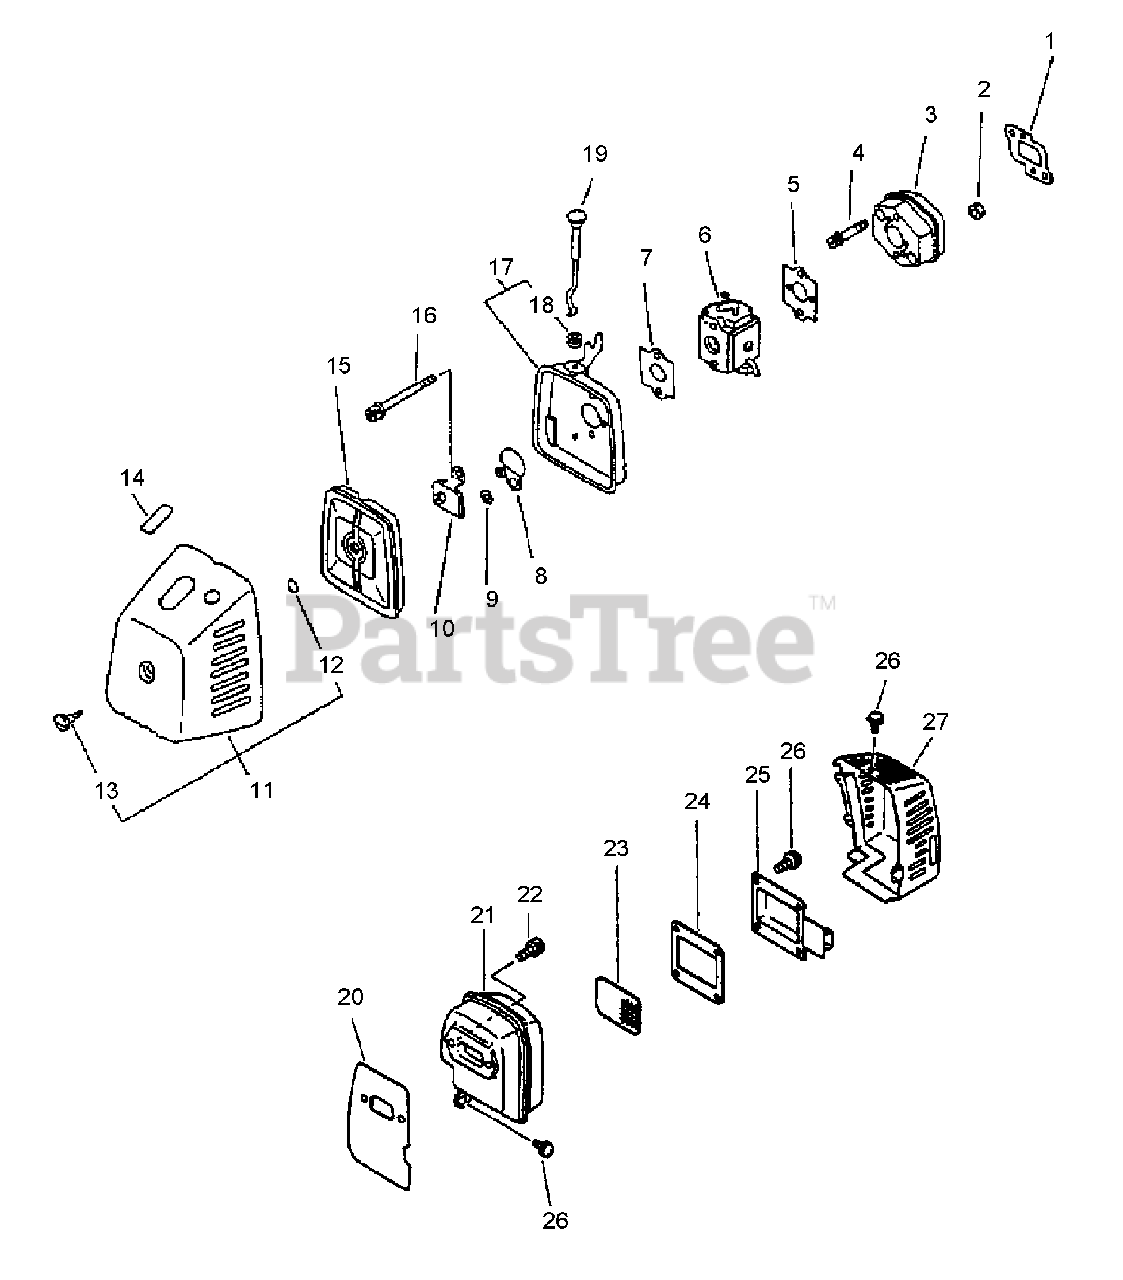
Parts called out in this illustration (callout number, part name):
1	GASKET, INTAKE
3	INSULATOR, INTAKE
4	SCREW - 5X25
5	GASKET, INTAKE
6	CARBURETOR WT-74A
6	CARBURETOR WT-297
6	CARBURETOR WT-415A
7	SPACER
8	SHUTTER, CHOKE
9	WASHER - 5
10	PLATE, PREVENT
11	AIR FILTER COVER ASSY
12	O-RING - 4
14	LABEL - CHOKE
15	FILTER, AIR
16	SCREW - 5X57
16	SCREW - 5X60
17	AIR FILTER CASE ASSY
19	ROD, CHOKE
20	GASKET, EXHAUST
21	MUFFLER
22	SCREW - 5X20
23	SCREEN, SPARK ARRESTOR
24	GASKET, EXHAUST
25	GUIDE, EXHAUST
26	SCREW - 4X10
27	COVER, EXHAUST
